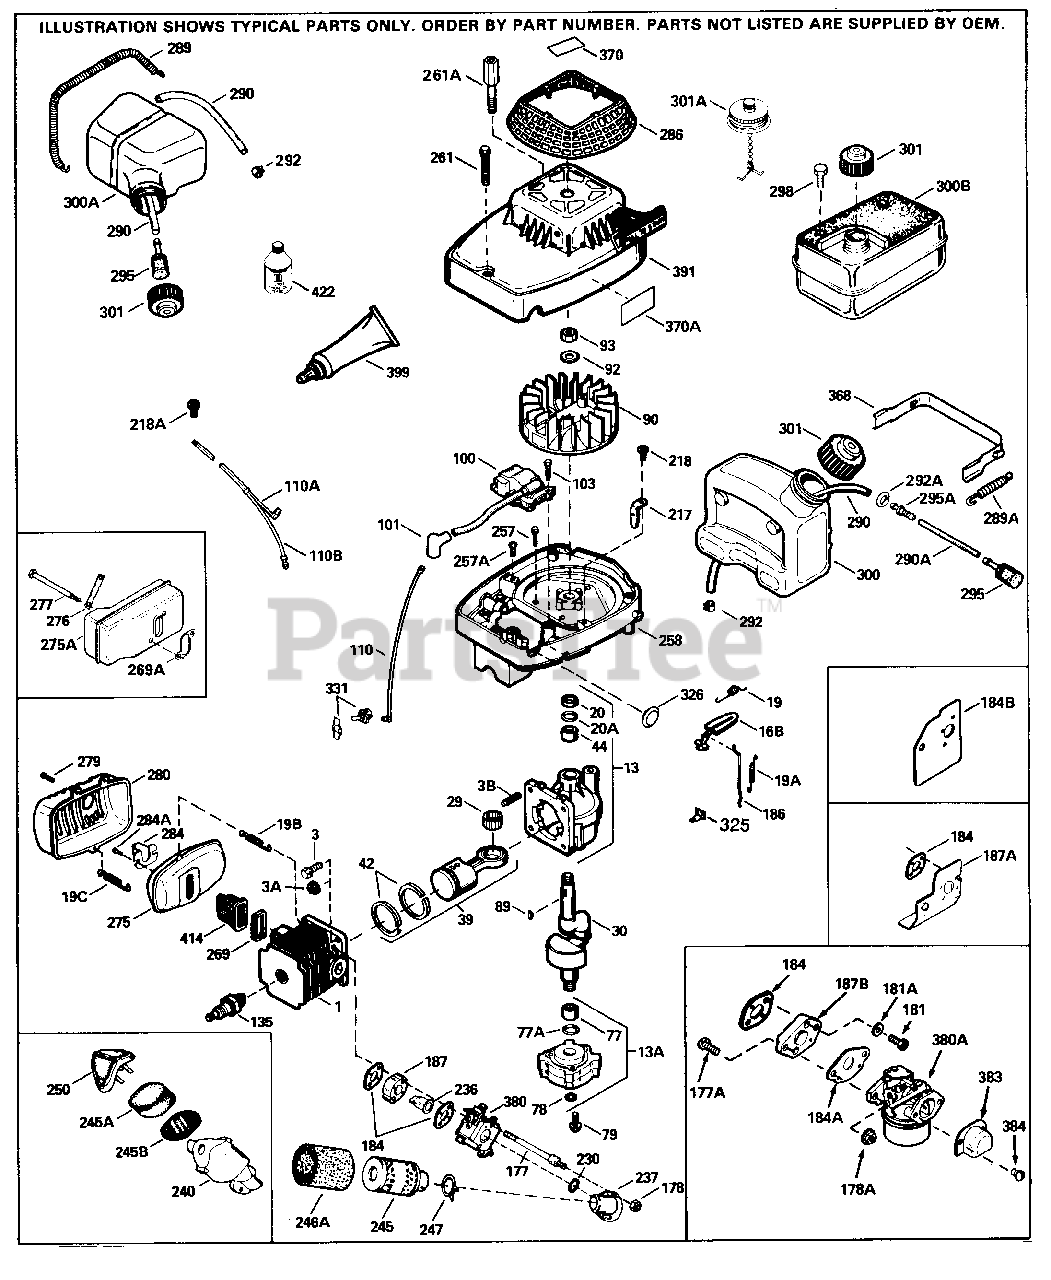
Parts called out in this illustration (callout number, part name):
1	"Cylinder NOTE: This cylinder is no lo nger available. If it is required, t he engine must be short blocked. See Engine & Short Block Replacement Lis t.
3A	Nut, Flange Whiz-Lock, 1/4-20
3B	Stud, Cylinder
13	Crankcase Assy. (Incl. 3B, 20, 20A & 44) NOTE: This Crankcase Ass'y.i s no longer available. If it is requ ired,the engine must be short blocked . See Engine & Short Block Replaceme nt List.
13A	Cover Assy., Crankcase (Incl. 77, 77A & 78) NOTE: This Crankcase Cover A ss'y. is no longer available. If it is required,the engine must be short blocked. See Engine & Short Block Re placement List.
20	Seal, Oil
20A	Retainer, Bearing (Used as required)
29	Bearing Set, Needle (23 needles) NOTE : Bearing 530154 is no longer availa ble. If it is required, the engine m ust be short blocked. See Engine & S hort Block Replacement List.
30	Crankshaft NOTE: This crankshaft is nolonger available. If it is require d, the engine must be short blocked. See Engine & Short Block Replacement List.
39	Piston & Rod Assy. (Incl. 29 & 42) NO TE: This piston & rod assembly is no longer available. If itis required, the engine must be short blocked. S ee Engine & Short Block Replacement L ist.
42	Ring Set, Piston
44	Bearing, Cartridge
77	Bearing, Cartridge
77A	Retainer, Bearing (Use as required)
78	Seal, Oil
79	Screw, 1/4-20 x 3/4"
89	Key, Flywheel
90	Flywheel
92	Washer, Belleville
93	Nut, Flywheel, 3/8-24
100	Solid State Assy. (Incl. 101)
101	Cover, Spark plug
103	Screw, 10-24 x 1"
110	Wire, Ground
135	Plug, Spark (RCJ-8Y)
177A	Screw, 1/4-20 x 3/4"
178A	Nut, Hex, 1/4-20
181	Connecting Rod Screw
184	Gasket, Carburetor (.031 thick)
184A	Gasket, Carburetor (.062 thick)
186	Link, Governor
187A	Baffle, Air
187B	Spacer, Carburetor
257	Screw, 10-24 x 5/8"
257A	Screw, 8-32 x 1/2"
258	Base, Blower housing
261	Screw, 8-32 x 1-9/16"
380A	Carburetor (Incl. 184A) (Refer to Div ision 5, Section A, page 166 or Fiche 24, Grid F-1 for breakdown)
383	Baffle, Air
384	Screw, 10-32 x 3/8"
391	Rewind Starter & Housing Ass'y. Refe r to Division 5, Section C, page 33 o r Fiche 24, Grid G-1 for breakdown
399	Gasket Eliminator (Use as required)
422	2-Cycle Oil with Fuel Stabilizer - 8 oz.
